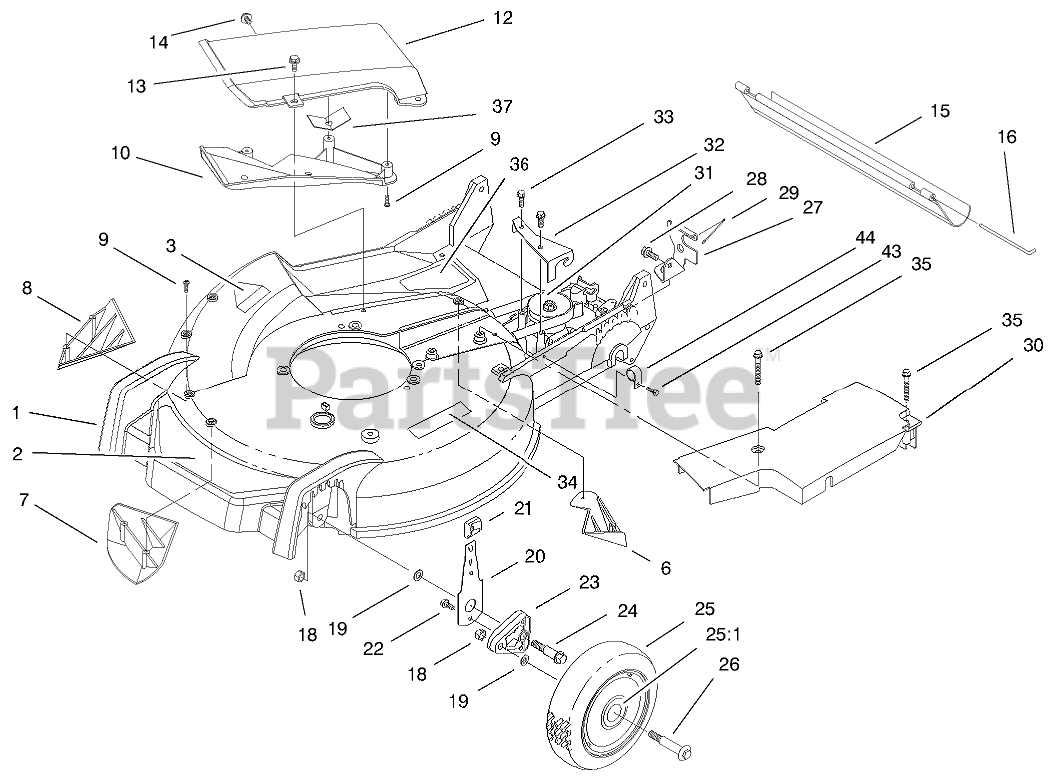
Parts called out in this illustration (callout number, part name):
1	HOUSING
2	DECAL - DECK
3	DECAL-DANGER
6	KICKER-REAR
7	KICKER-FRONT
8	KICKER-RH
9	SCREW-PPH
10	Deflector-Recycler
11	Guard-Cover
12	COVER W/DEFLECTOR
13	SCREW-HWH
14	SCREW AND WASHER ASM
15	SHIELD-TRAILING
16	ROD-SHIELD
18	NUT-LOCK
19	WASHER
20	FRONT SPRING ARM ASM
21	KNOB-ARM
22	SCREW-HWH
23	ARM-PIVOT, FRONT
24	BOLT-SHOULDER
25	WHEEL AND TIRE ASM
25:1	BUSHING
26	BOLT-WHEEL
27	Bracket-Adj. Trac
28	SCREW-HWHTF
29	RETAINER-CABLE
30	COVER-BELT
31	GEARCASE ASM
32	Bracket-Guide
33	SCREW-HWHTF
34	DECAL-WARNING
35	SCREW-HHFTF
36	DECAL - DANGER
37	Screw-PPH
